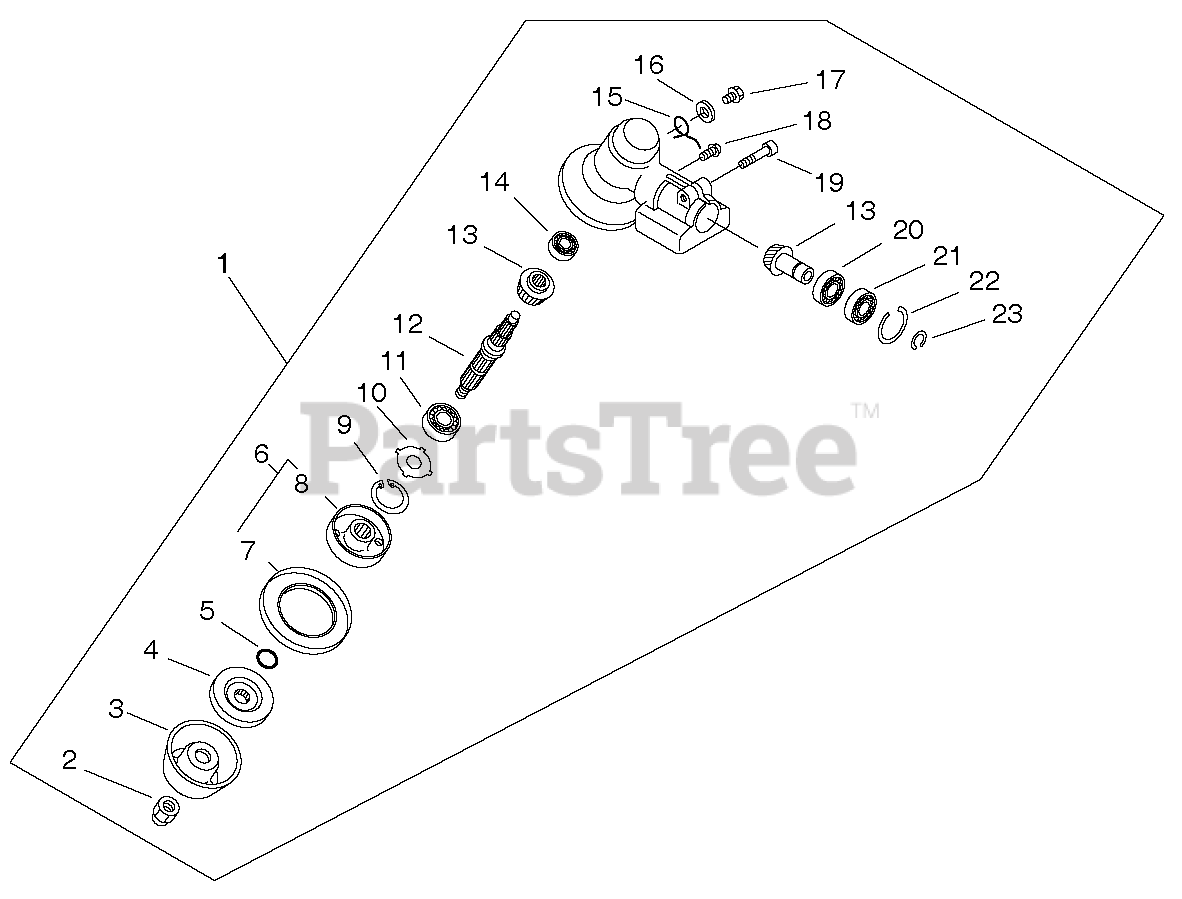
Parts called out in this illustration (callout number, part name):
1	GEAR CASE ASSY
2	NUT - 10
4	ADAPTOR, BLADE - LOWER
5	O-RING - 12
6	BLADE ADAPTER KIT
7	RETAINER, BLADE
8	ADAPTOR, BLADE - UPPER
9	RING, RETAINING - 32
11	BEARING, BALL - 6201
12	GEAR - SHAFT
13	GEAR SET
14	BEARING, BALL - 629
16	WASHER - 8
17	BOLT - 8X8
18	SCREW - 5X10
19	SCREW - 6X30
20	BEARING, BALL - 6001
21	BEARING, BALL - 6001Z
22	RING, RETAINING - 28
23	RING, RETAINING - 12
